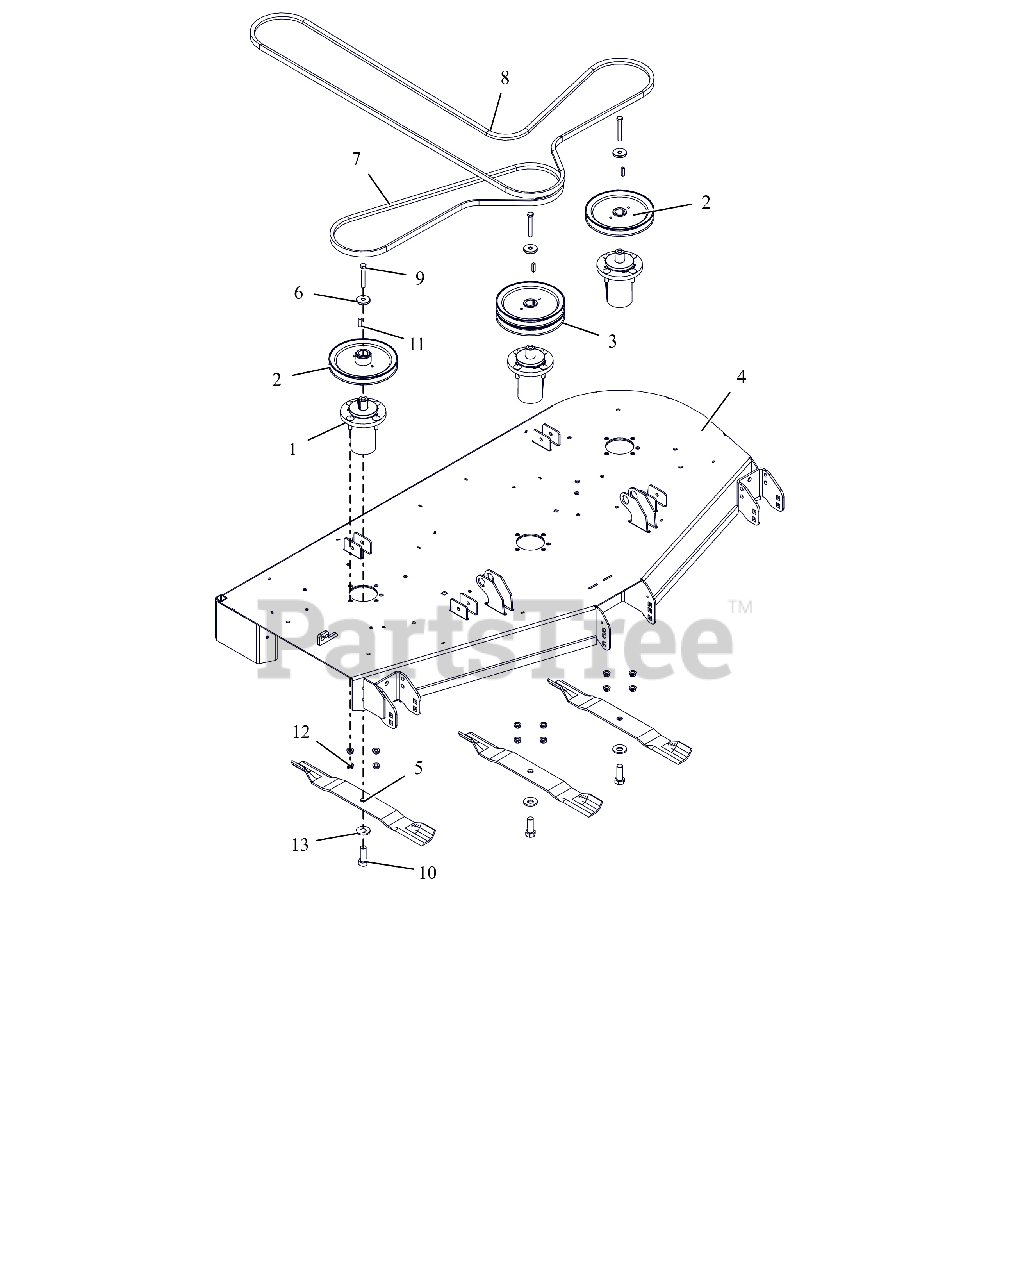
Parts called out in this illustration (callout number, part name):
1	ASM, MAINT FREE ALUM SPINDLE
2	PULLEY, V-7.50 OD X 1"ID
3	PULLEY, DOUBLE 1"X7.50"&7.50" (BLACK)
4	KIT,DECK-60" W/DECALS-ARIENS
5	BLADE, 20.5"
6	RETAINER, SHEAVE
7	V-BELT, B-COGGED
8	V-BELT, HB SECTION
9	BLT-HEX .38-16X2.75 GR8 YWZC
10	BLT-HEX .62-18X1.75 GR8 YWZC
11	KEY, SQ .25X.25X1.00 RC 40-50
12	NUT-LK-CTR-FLG .38-16 YWZC
13	WSHR-BLVL .669X1.535X.138
